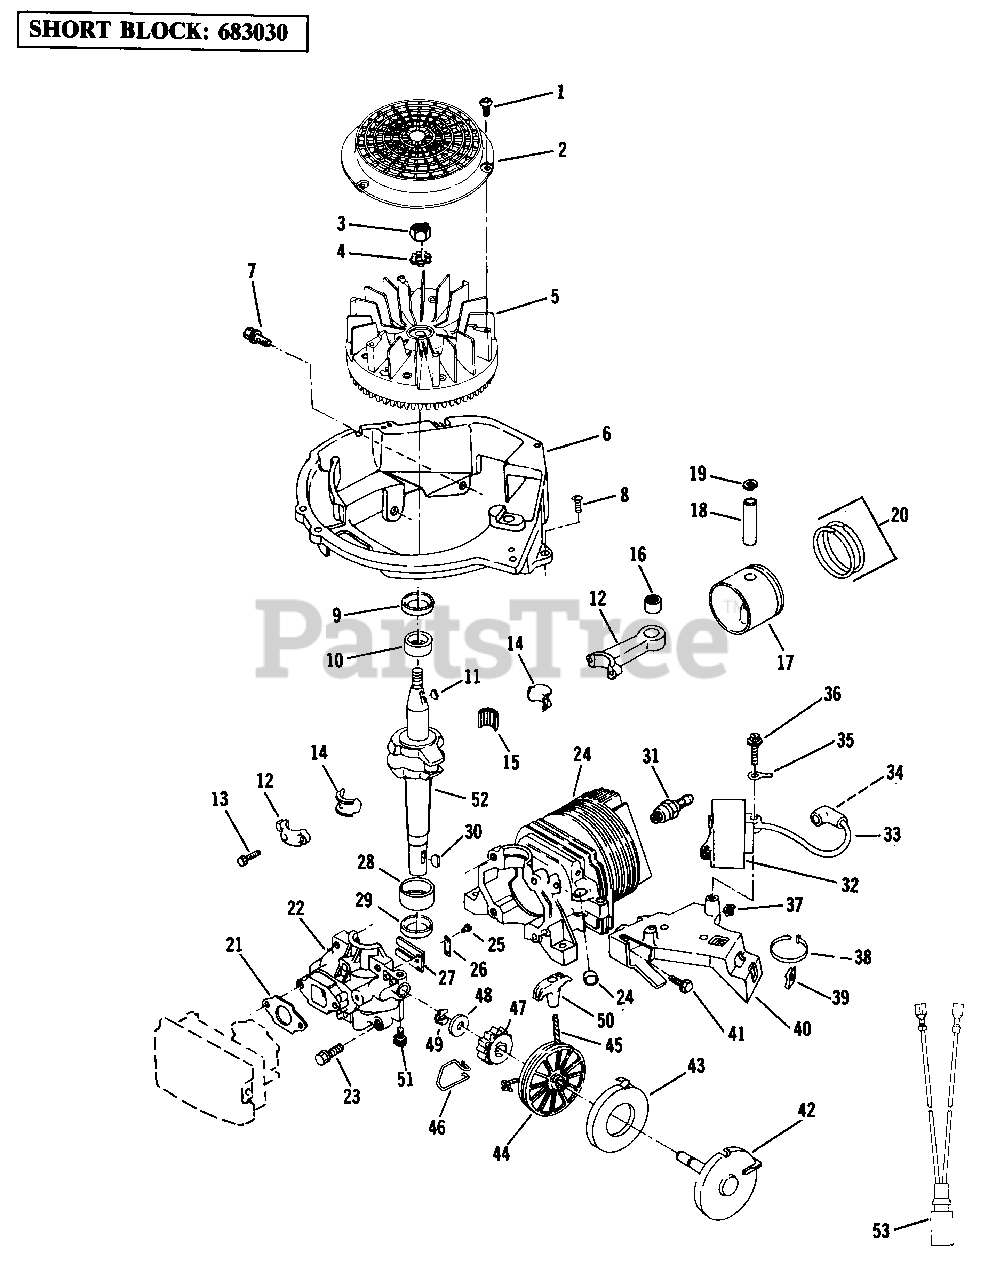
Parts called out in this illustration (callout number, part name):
1	Screw
2	Screen-Flywheel
3	Nut-Flywheel
4	Lockwasher
5	Flywheel Assembly
6	Shroud Base
7	Screw
8	Screw-Shd. Base to C. D. Brkt.
9	Oil Seal-Upper
10	Bearing-Main-Upper
11	Key-Flywheel
12	Conn. Rod Assembly
13	Screw
14	Liner Split
15	Needle Bearing Set
16	Bearing Assembly
17	Piston and Ring Set
18	Wrist Pin
19	Retaining Ring
20	Ring Set
21	Gasket-Carburetor to Crankcase Cover
22	Cylinder and Crankcase Cover Assembly
23	Screw-Cover to Crankcase
24	Plug
25	Screw-Reed to C'case Cover
26	Plate-Reed Hold Down
27	Reed
28	Bearing-Main-Lower
29	Oil Seal-Lower
30	Key-Clutch Hub
31	Spark Plug
32	C.D. Ignition Module and Lead Assembly
33	High Tension Lead
34	Spring Terminal
35	Terminal-Ground Lead
36	Screw-C.D. Mounting
37	Grommet-C.D. Bracket
38	Tie Strap
39	Clip-"U"
40	Bracket-Ignition Mounting
41	Screw
42	Spring Cup and Pin Assembly
43	Spring and Retainer Assembly
44	Pulley
45	Rope
46	Spring-Drag
47	Pinion
48	Washer
49	Retainer
50	Handle-Starter
51	Set Screw-Starter Assembly
52	Crankshaft
53	Wire Harness-Engine
